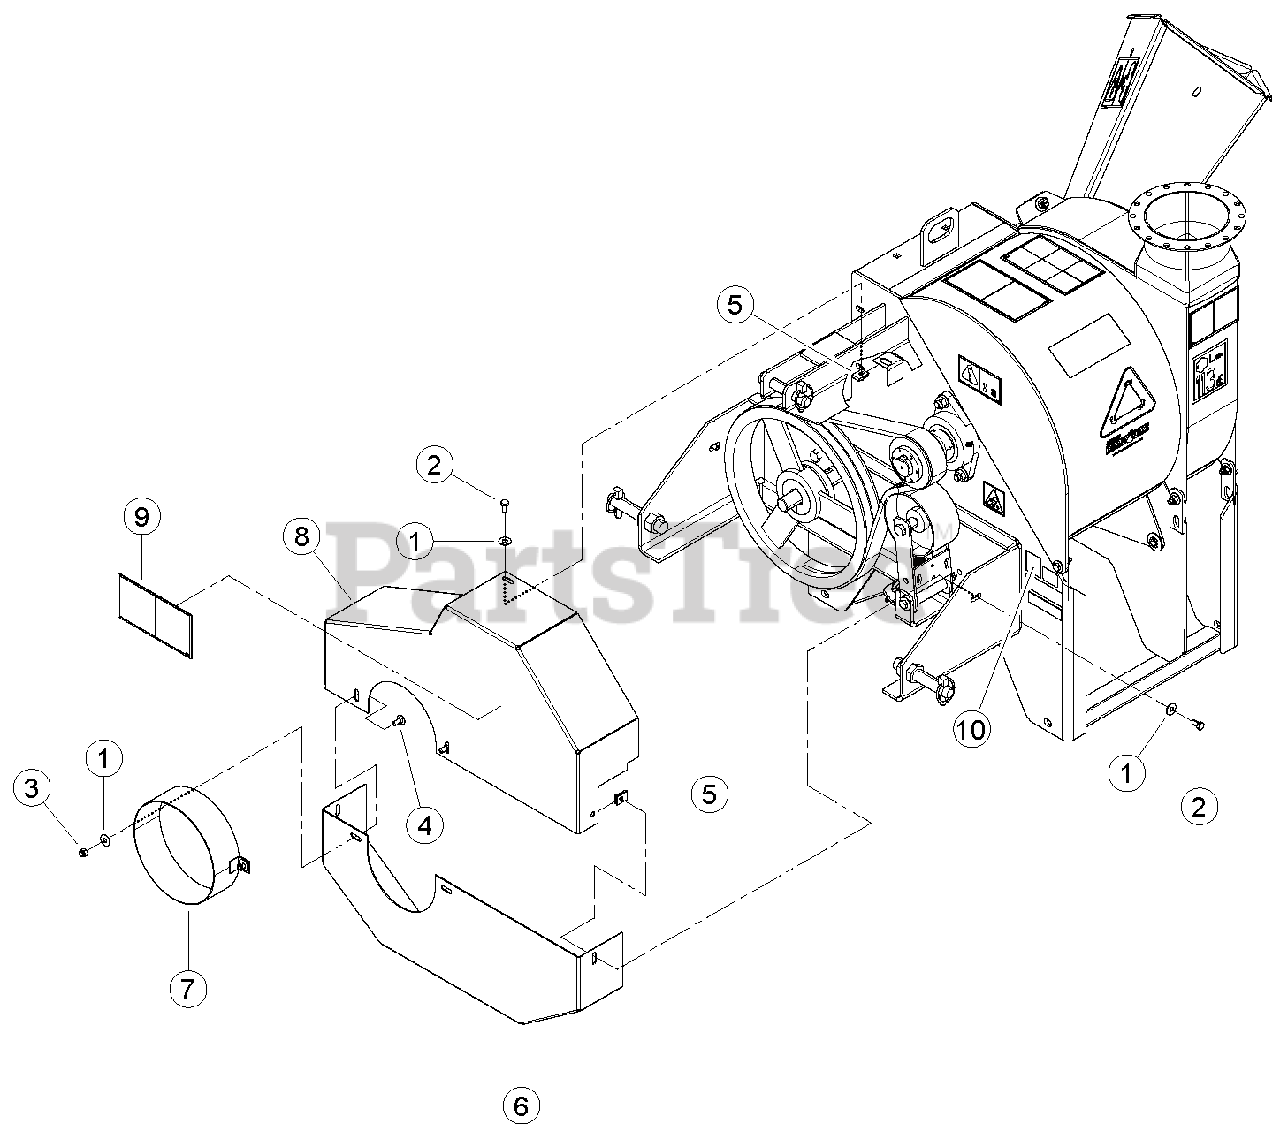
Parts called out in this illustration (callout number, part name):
1	WASHER, 5/16 FLAT ZP
2	BOLT, 5/16 X 5/8 HEX HD GR5 ZP
3	NUT, 5/16 NE NYLOCK ZP
4	BOLT, 5/16 X 3/4 CRG GR5 NC ZP
5	NUT, 5/16-18 TINNERMAN U-TYPE
6	SHIELD, BOTTOM BELT
7	WELDMENT, JOINT SHIELD
8	ASSEMBLY, GUARD PTO, SERVICE PART
9	DECAL, PTO DANGER ISO
10	DECAL, ECHO BEAR CAT QR CODE
